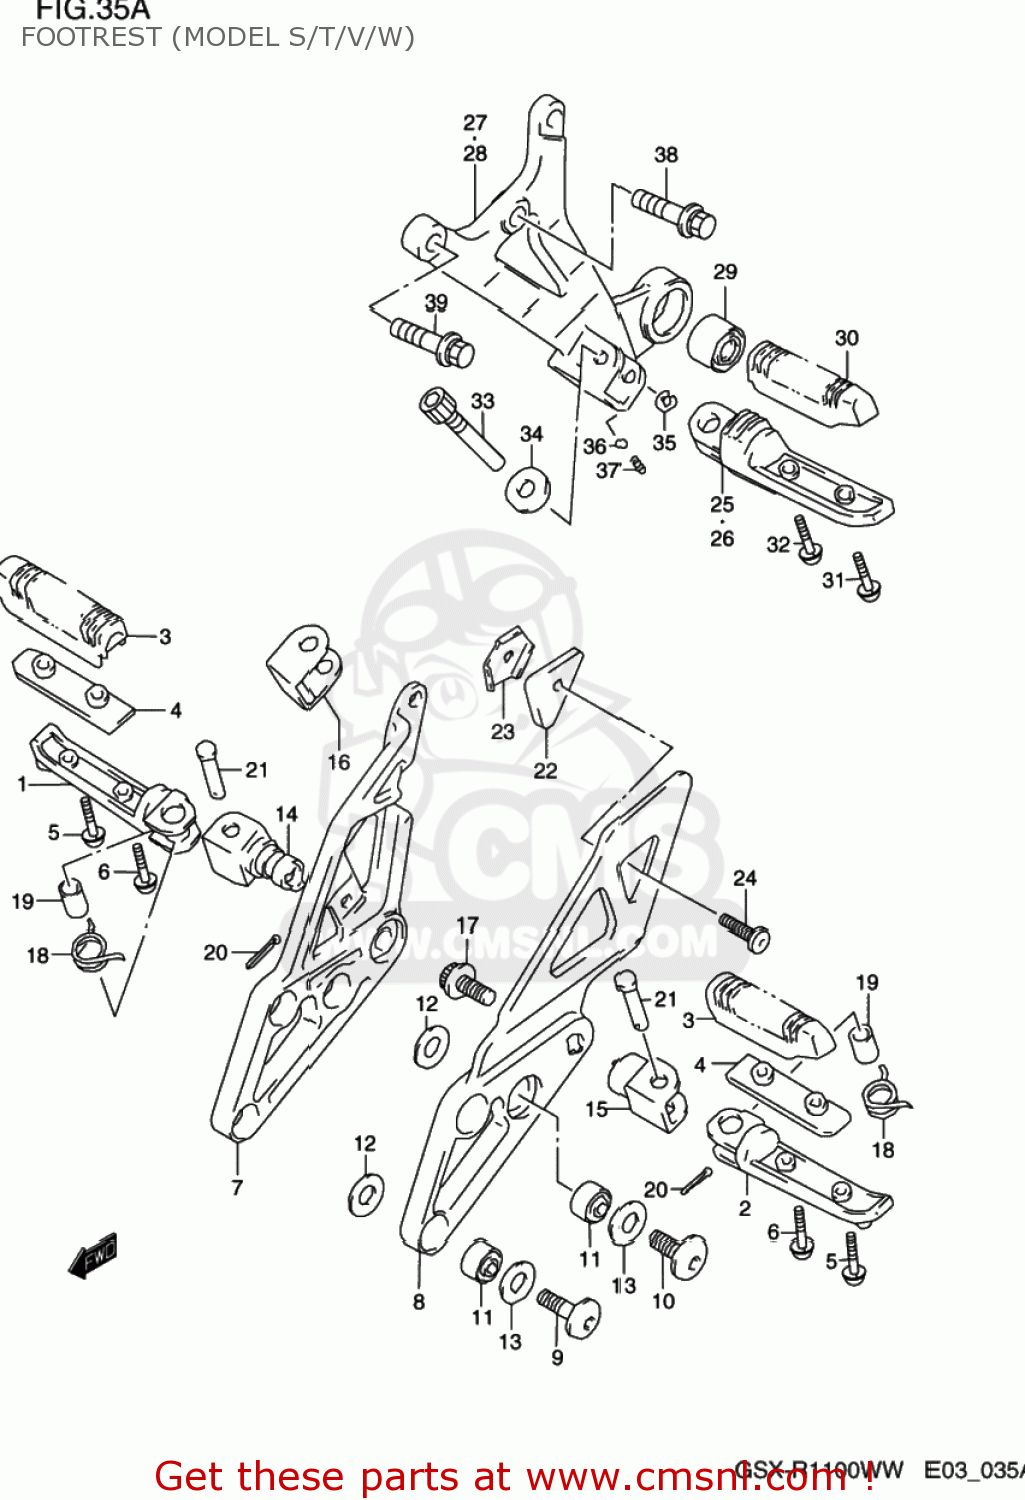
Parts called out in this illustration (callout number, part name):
1	BAR,FOOTREST,R
2	BAR,FOOTREST,L
3	RUBBER,FOOTREST
4	BAR,FR FOOTREST NO.2
5	SCREW
6	SCREW
7	BRACKET,FOOTREST,R
8	BRACKET,FOOTREST,L
9	BOLT L:30
10	BOLT(8X25)
11	BUSH(12X20X16)
12	WASHER (8.2X24X1.6)
13	WASHER(12.6X24X1.9)
14	HOLDER,FOOTREST
15	HOLDER,FOOTREST,L
16	CUSHION,FR FOOTREST
17	BOLT(10X24)
18	SPRING
19	SPACER(8.1X12X22)
20	PIN 20X15
21	PIN
22	WEIGHT,FOOTREST BRACKET,L
23	COVER,FOOTREST WEIGHT
24	SCREW(6X20)
25	BAR,PILLION FOOTREST,R
26	BAR,PILLION FOOTREST,L
27	BRACKET,PILLION FOOTREST,R
28	BRACKET,PILLION FOOTREST,L
29	BUSHING 10X28.1X19
30	RUBBER,FOOTREST
31	SCREW
32	SCREW
33	BOLT,PILLION FOOTREST
34	WASHER
35	E.RING
36	BALL
37	SPRING
38	BOLT
39	BOLT
